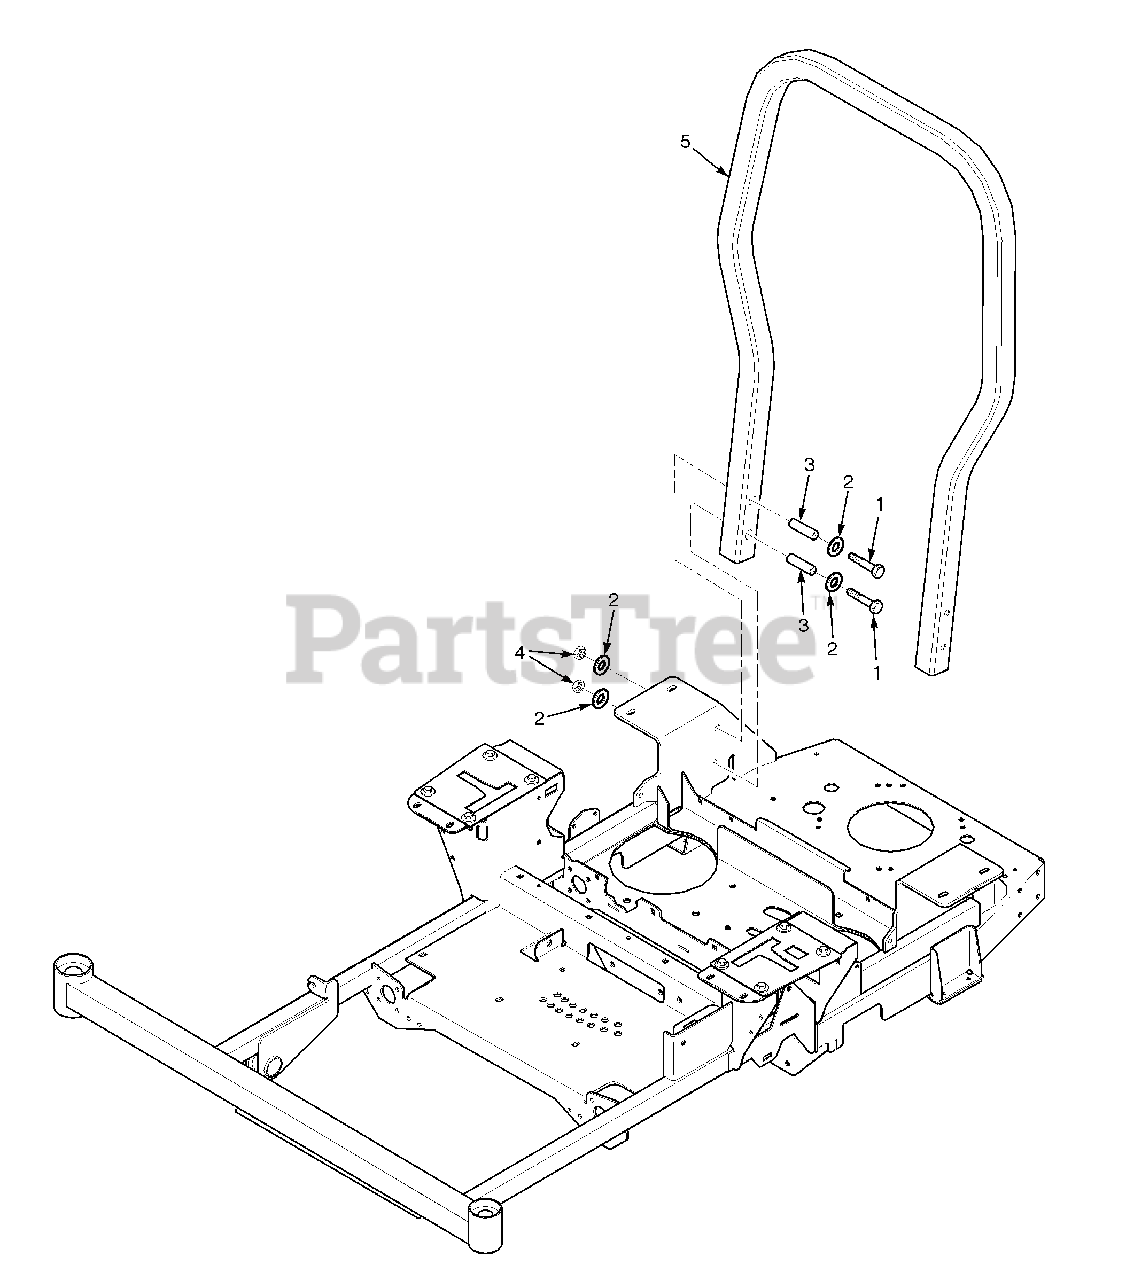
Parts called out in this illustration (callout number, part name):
1	Bolt, Hex Head 1/2-13 x 3-1/4" Gr. 8
2	Flatwasher, 1/2-.562 x 1.375 x .109
3	Bushing, SFZ ROPS
4	Nut, Center Lock 1/2-13
5	ROPS, SFZ
